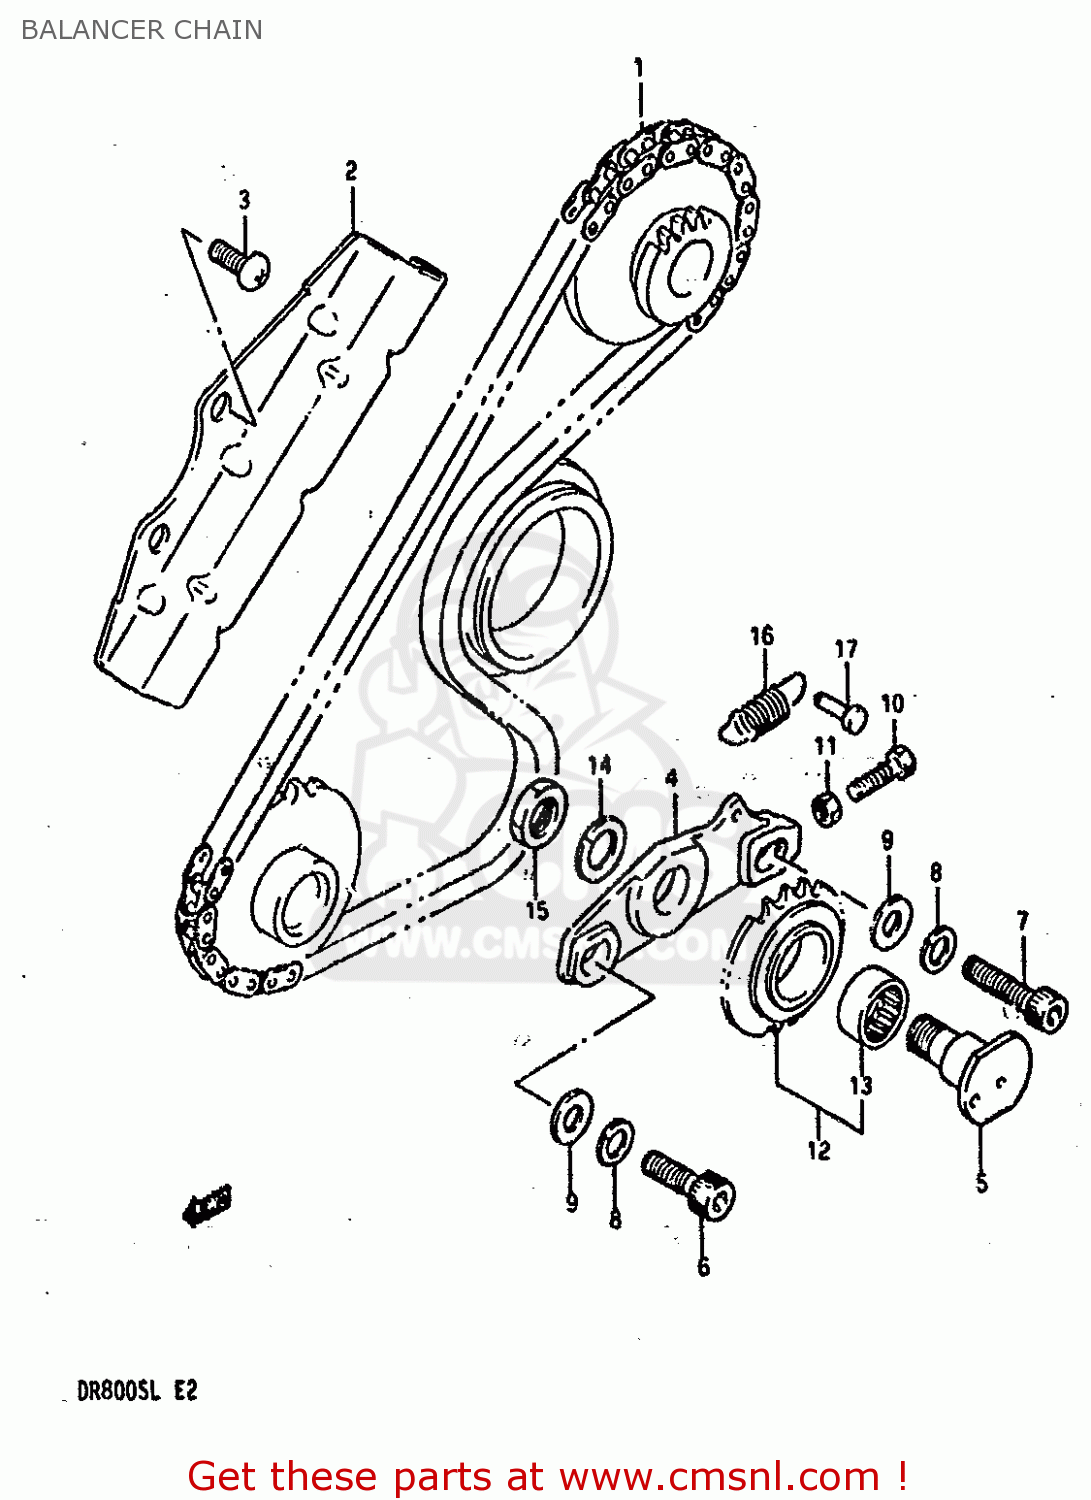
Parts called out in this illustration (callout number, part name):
1	CHAIN,BALANCER
2	GUIDE,BALANCER CHAIN
3	SCREW
4	BRACKET, CHAIN TENSIONER
5	SHAFT,BALANCER CHAIN TENSIONER
6	BOLT(8X22)
7	BOLT, REAR (8X30)
8	LOCK WASHER
9	WASHER
10	BOLT 5X20
11	NUT
12	SPRKT,BALANCER CHAIN TENSIONER
13	BEARING(17X23X12)
14	WASHER,LOCK 12
15	NUT
16	SPRING
17	RIVET
